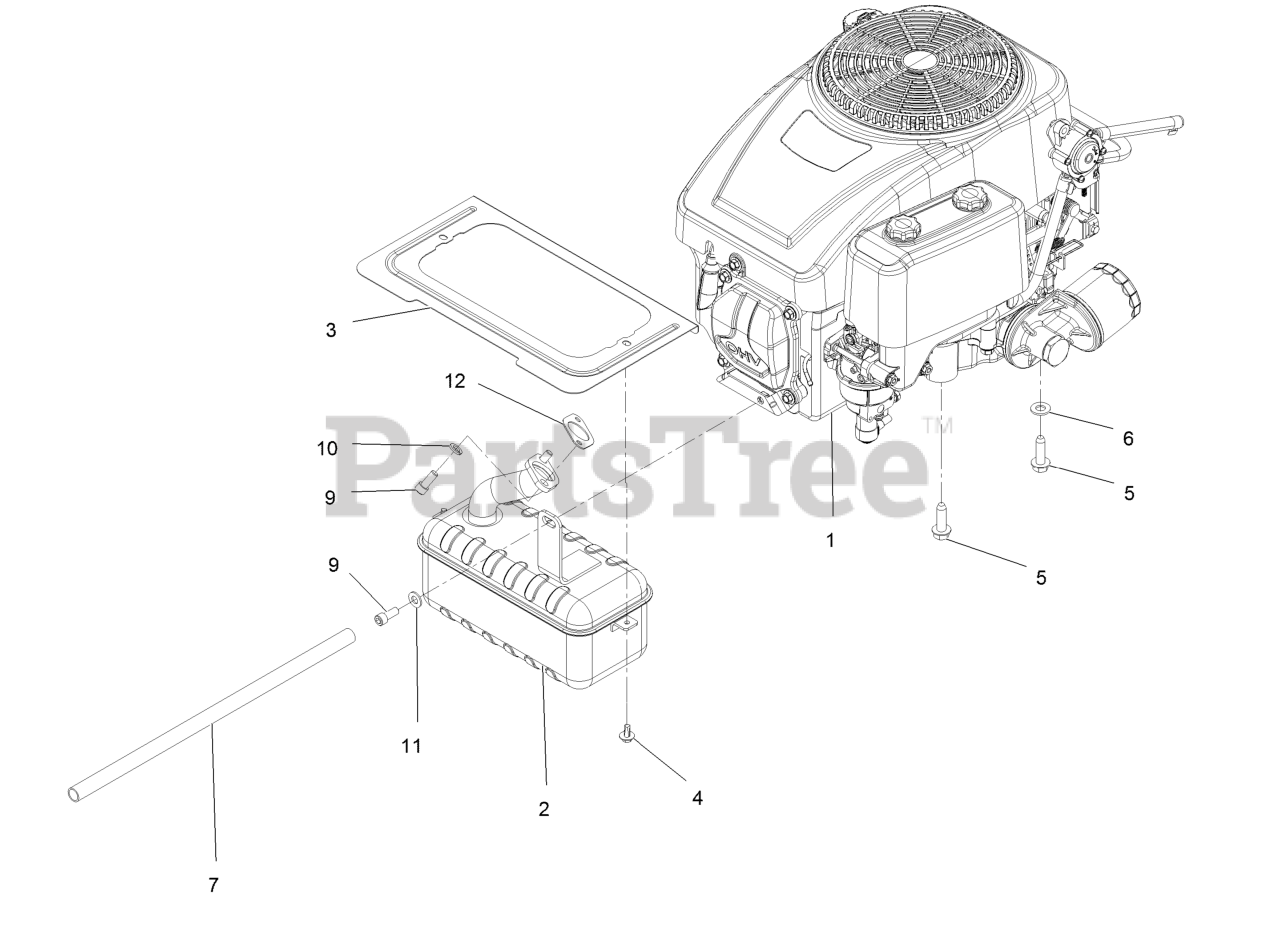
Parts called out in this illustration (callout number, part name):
2	MUFFLER
3	SHIELD-HEAT
4	SCREW-HHFTF
5	SCREW-THD
6	WASHER-FLAT
7	TUBE-DRAIN, OIL
9	SCREW-HSH
10	WASHER-LOCK
11	WASHER-PLAIN
12	GASKET-EXHAUST
